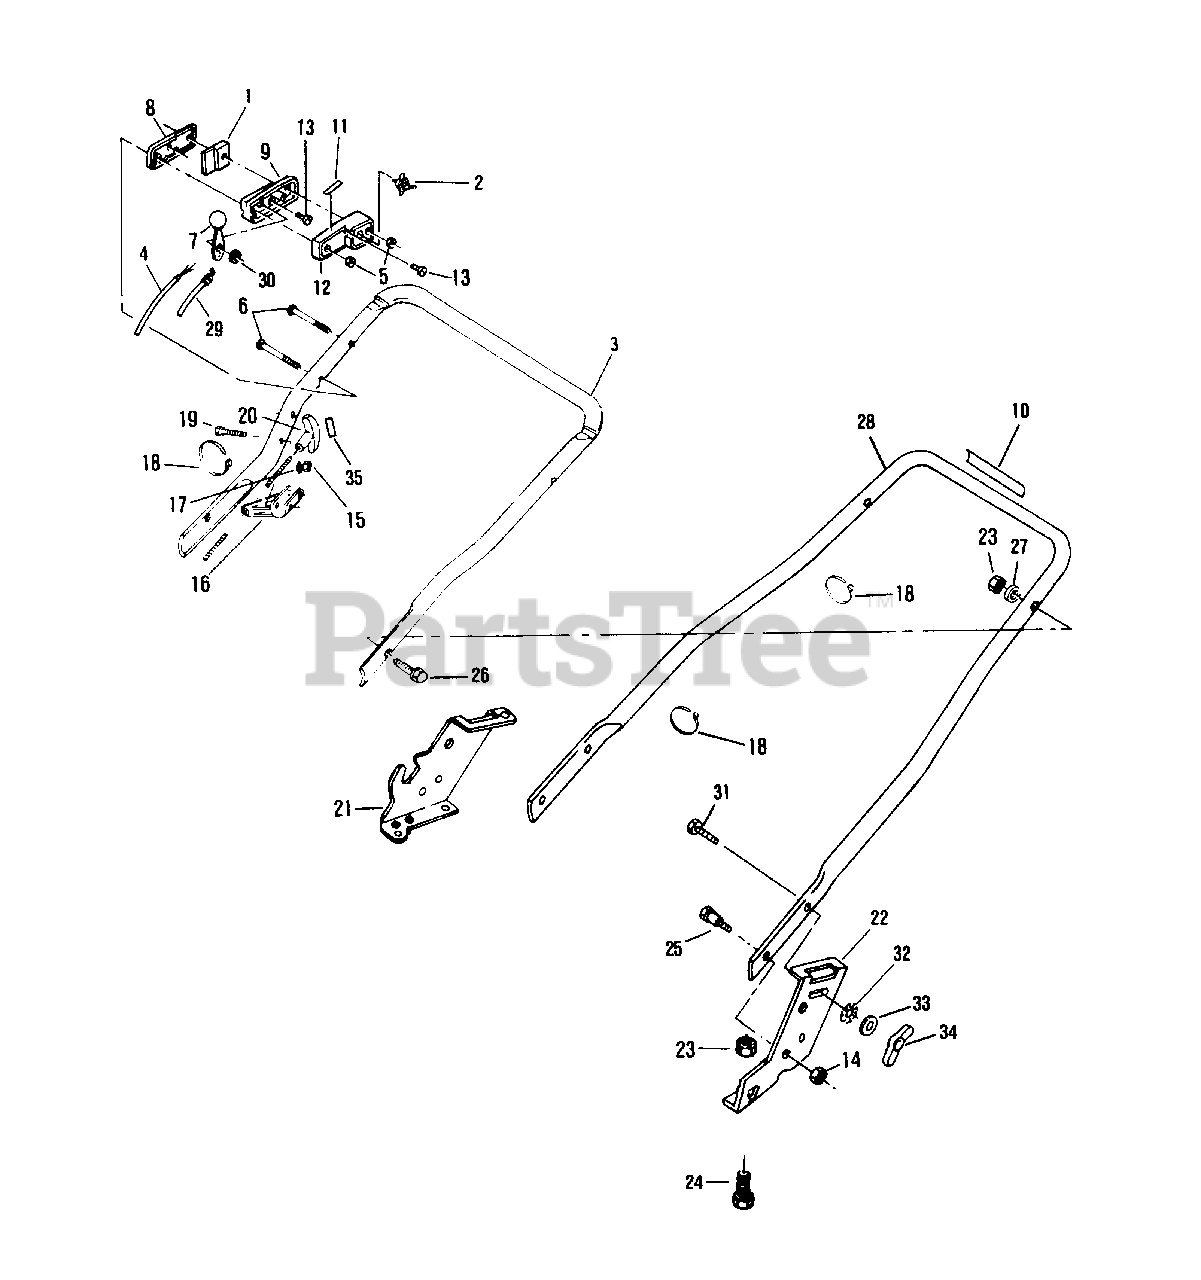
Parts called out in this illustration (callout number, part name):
1	Escutcheon Plate
2	Switch Assembly
3	Top Handle
4	Wiring Harness
5	Nut-Hex-Centerlock
6	Screw
7	Lever/Knob
8	Control Case-Outer
9	Case-Throttle Center
10	Decal
11	Decal-Throttle Control
12	Case-Throttle,Inner
13	Screw
14	Nut-Handle to Handle Bracket
15	Locknut
16	Rope Guide Assembly
17	Washer
18	Tie Wrap
19	Screw-Truss Head
20	Handle-Starter
21	Handle Bracket-R.H.
22	Handle Bracket-L.H.
23	Nut-Handle Bracket and Handle
24	Bolt-Handle Bracket to Housing
25	Bolt-Handle to Handle Bracket
26	Screw-Handle
27	Washer
28	Handle-Bottom
29	Cable-Throttle
30	Washer-Spring
31	Screw
32	Lockwasher
33	Washer
34	Wing Nut
35	Clip-Starter Handle
